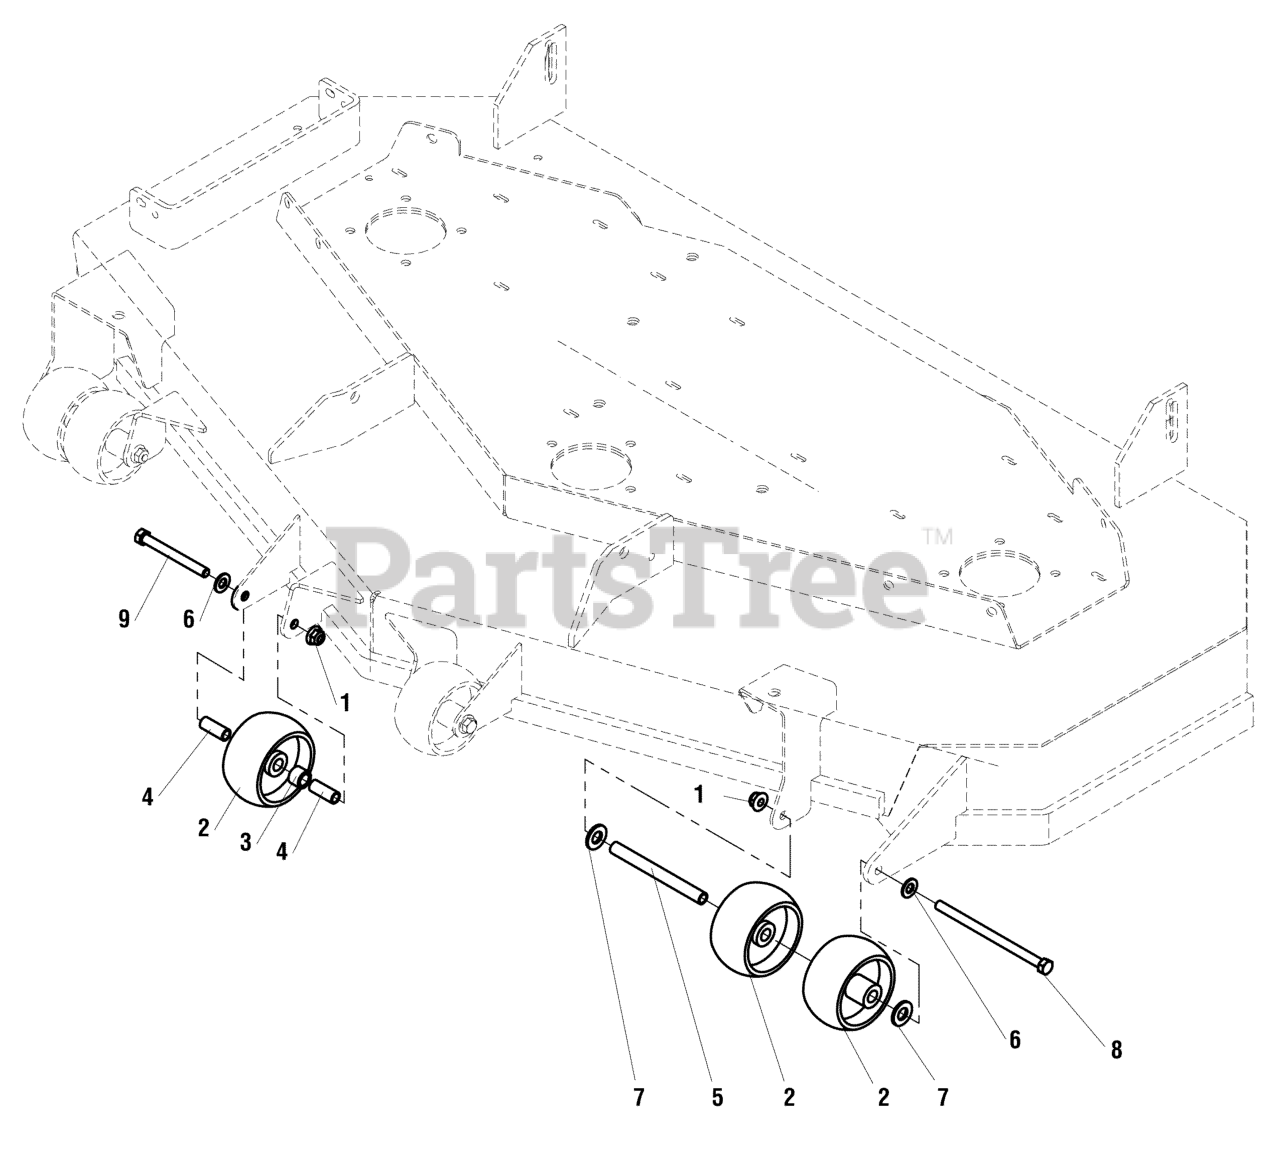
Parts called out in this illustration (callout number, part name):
1	NUT, 3/8-16 HEX NYLOCK FLANGE
2	WHEEL- 2.00 WIDE 3.88 DIA 0.531ID POLY
3	SPACER, .51 X .75 X .56
4	SPACER, .38 X .50 X 1.25, CZ
5	SPACER, .38 X .50 X 5.06
6	WASHER, 3/8 SAE
7	WASHER, 1/2 SAE
8	BOLT, 3/8-16 X 6" GD5 CZ
9	BOLT, 3/8-16 X 3-1/2" GD5 CZ
